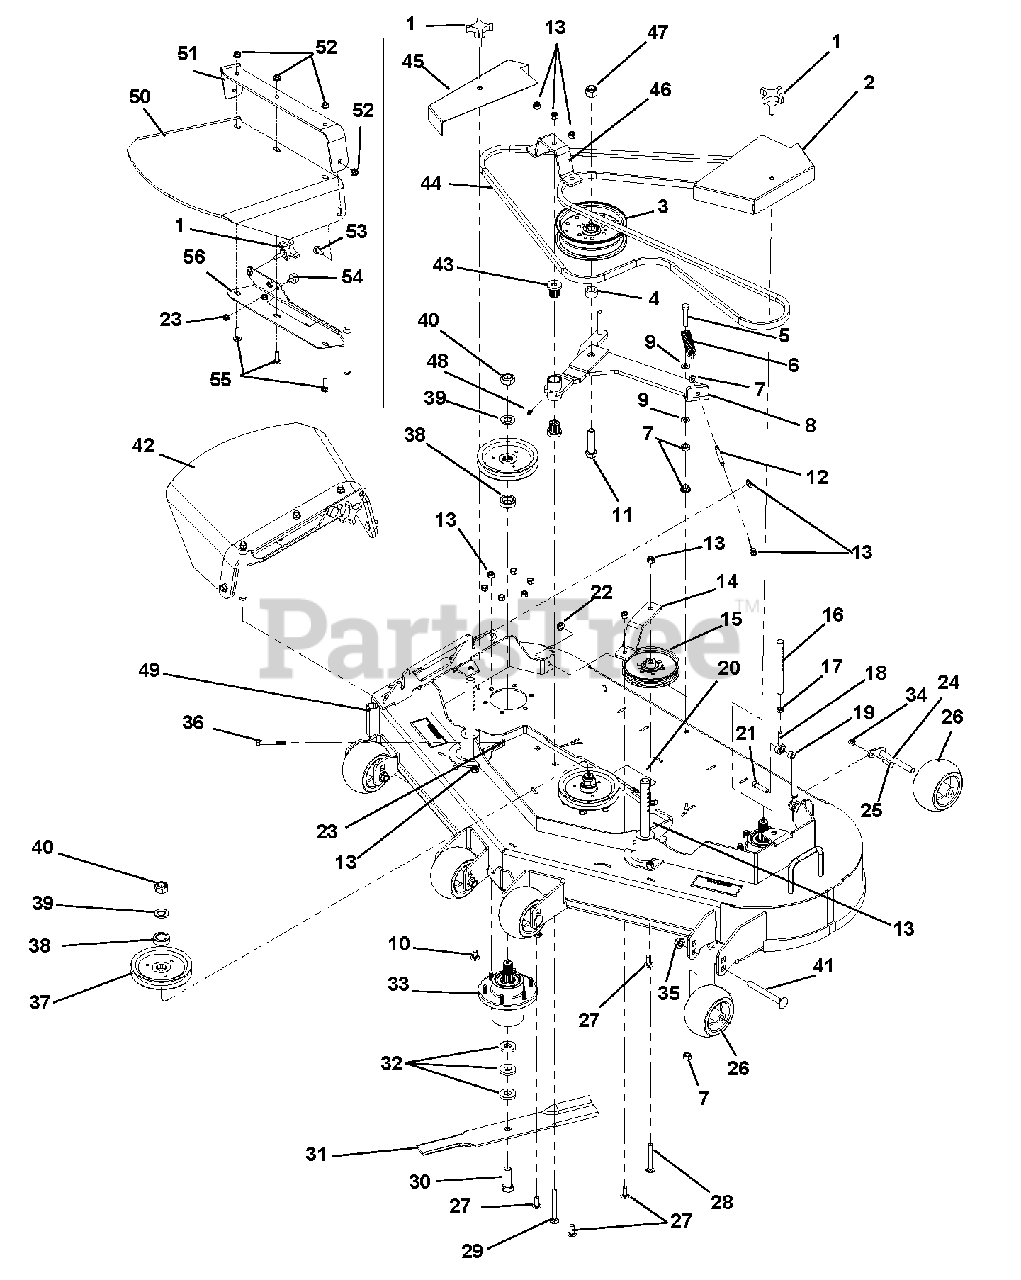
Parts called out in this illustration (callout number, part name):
1	KNOB, .38 x 1.25- 4 PRONG
2	SHIELD, LH SPINDLE 52 FLWLK (988148)
3	PULLEY, FLAT 6.00 X .635 W/BRG
4	BUSHING, .688 X 1.13 X .55
5	BOLT, 7/16-14 X 2.00 HEX 5 Y
6	SPRING, EXT .875 X .125 X 4.25 Y
7	LOCKNUT, 3/8-16 WHIZ Y
8	WLDT, IDLER ARM 48/52 FLOAT WALK
9	WASHER, .406 X .813 X .065 FLAT
10	BOLT, RDHDSHSQNK .38-16 X .75 G5
11	BOLT, HEX .62-11X2.50 GR5Y
12	ROD, THREADED ADJUSTMENT
13	LOCKNUT, 3/8-16 NYLOC Y
14	STRAP, IDLER 52/48 WALK
15	PULLEY, FLAT 5.00X.375 W/BRG
16	ROD, REAR HOC
17	NUT, JAM .375-24 YWZC REV
18	ROD, END 3/8 RH REV
19	BSHG - SLV REV
20	ROD, FRONT HOC
21	BOLT, HEX .38-16 X 1.50 GR5
22	NUT, LK-TOP-FLG .375-16 YWZC REV
23	LOCKNUT, 5/16-18 WHIZ Y
24	PIVOT, RETAINER WELD
25	BOLT, 1/4-20 X 1.00 SQU SN Y
26	WHEEL, GAGE
27	5BOLT, 3/8-16 X 1.00 CRG 5 SN Y
28	BLT, RDHD SQNK .38-16 X 3.0 GR5YZ REV
29	BLT, 3/8-16 X 3.50 CRG 5
30	BOLT, 5/8-11 X 2.00 HEX 8 Y
31	BLADE, 18.000 X .80 LIFT (988148)
32	WASHER, BLADE
33	ASSY, SPINDLE HOUSING
34	Nut, 1/4" FLANGE PREVAILING TOR
35	LOCKNUT 1/2 W/FLANGE
36	BOLT, 5/16-18 X 2.50 HEX 8 Y
37	PULLEY, SPLINE SPINDLE SHFLWLK
38	SPACER, 1.500 X 1.000 X .510 Y
39	WASHER, .75 X 1.3125X .113
40	LOCKNUT, 3/4-16 CROWN C
41	BOLT, 1/2-13 X 4.50 CRG 5 Y
42	ASSY, DISCHARGE SHIELD
43	BRG, FLG M10 X M25 X M27 FLUTED
44	BELT, HB 131.0 EL AMD (988148)
45	SHIELD, RH SPINDLE 52 FLWLK (988148)
46	STRAP, IDLER 52 FLOAT WALK (988148)
47	NUT, LK-NYL .625-11 YWZC REV
48	FTG, 1/4-28 STRGT GREASE ZERK
49	ASSY, 52" FLOAT DECK W/DECALS (988148)
50	SHIELD, WALK RUBBER DISCHARGE
51	STRAP, GRAVELY WLK RUBBER DIS
52	NUT, SPNLK-FLG .375-16
53	BOLT, RDHDSQNK .38-16 X 1.00 G5
54	BUMPER, RUBBER
55	BOLT, RDHDSQNK .38-16 X 1.25 G5
56	WLDT. DISCHARGE
